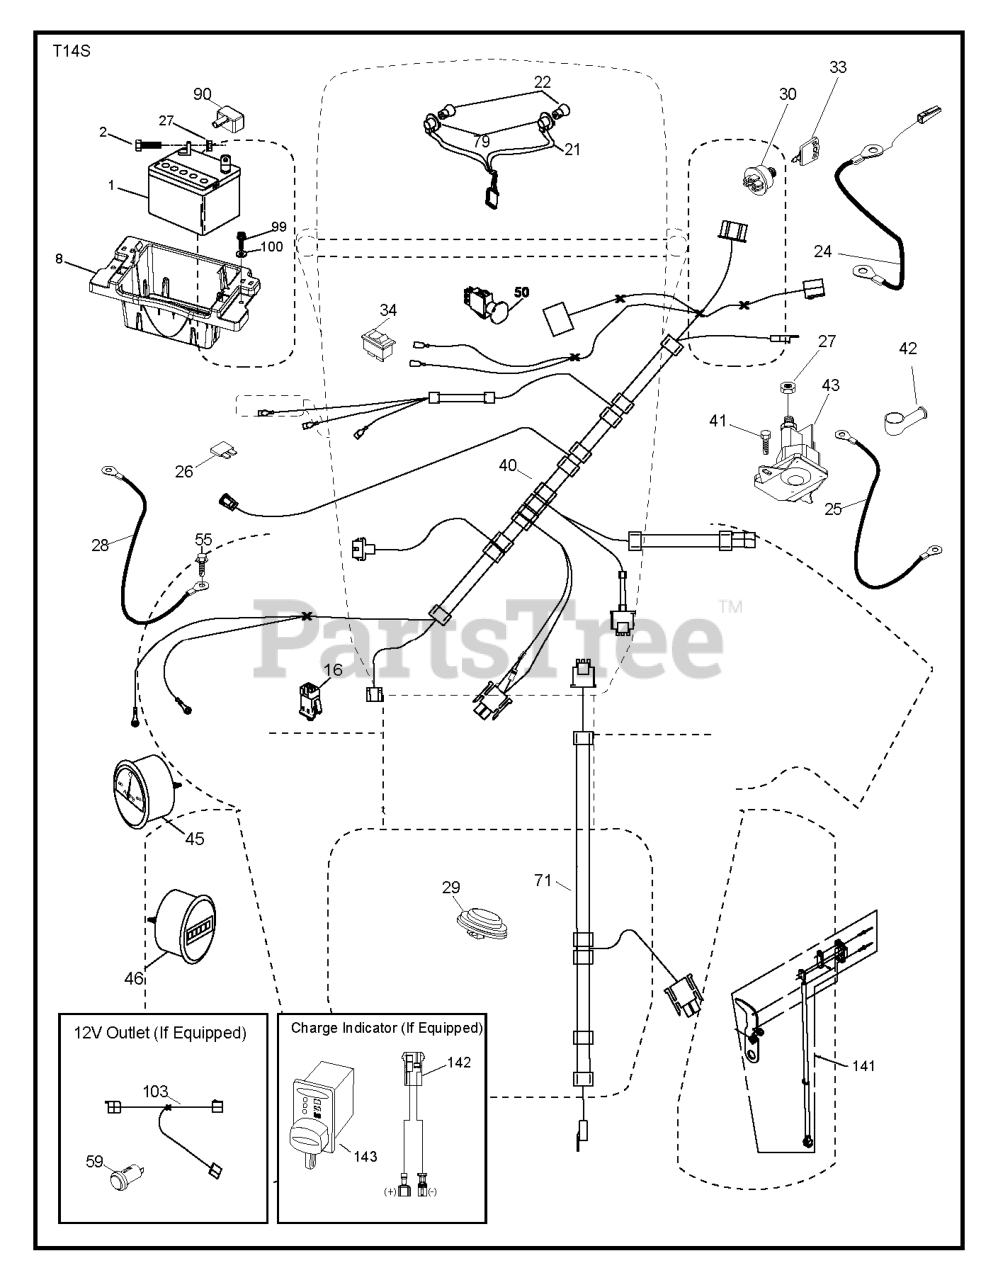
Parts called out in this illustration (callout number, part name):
1	Battery, Dry 30 Amp
2	BOLT.HEX.1/4.X.3/4.DICHROMATE
8	TRAY.ASM.BATTERY.FRT.TEX.CARB
16	SWITCH INTERLOOK PUSH-IN
21	HARNESS.LIGHT W/4152J BULBS
24	CABLE.FRBATT.W/WIRE.8GA.8
25	CABLE.STARTER.8GA.17.5
26	FUSE 20AMP
27	NUT
28	CABLE.GROUND.21"BLK.8GA.90T
29	SWITCH.SEAT.DELTA.OPC.
30	SWITCH.IGN.DELTA.W.LGH.ROS
33	KEY.CHAIN.BLISTER.PACK.GEN.USA
40	HARNESS.IGN.DASH.W/112V.PORT
41	SCREW
42	TERMINAL COVER
43	SOLENOID.W/BRASS.PLUNGER
45	GAUGE.AMMETER.SILVER/WHITE
46	GAUGE.HOUR.METER.SILVER/WHITE
50	RP.PTO.SWITCH.8 TERMINAL.BLACK
55	SCREW 5/16"
59	OUTLET.12-VOLT
71	HARNESS-CHASSIS SUB
79	BULB HOLDER ASM.
90	COVER.TERMINAL.BATTERY
91	STRAP.BATTERY.MOUNT.FRONT(2 2)
99	SCREW HEXWSHR 1/4-20X3/4
100	WASHER
103	HARNESS.PIGTAIL.12V.OUTLET.
141	KIT.G700/G730.ROS 71750
142	CHARGE.PORT.PIGTAIL HARNESS
143	CHARGE.PORT
